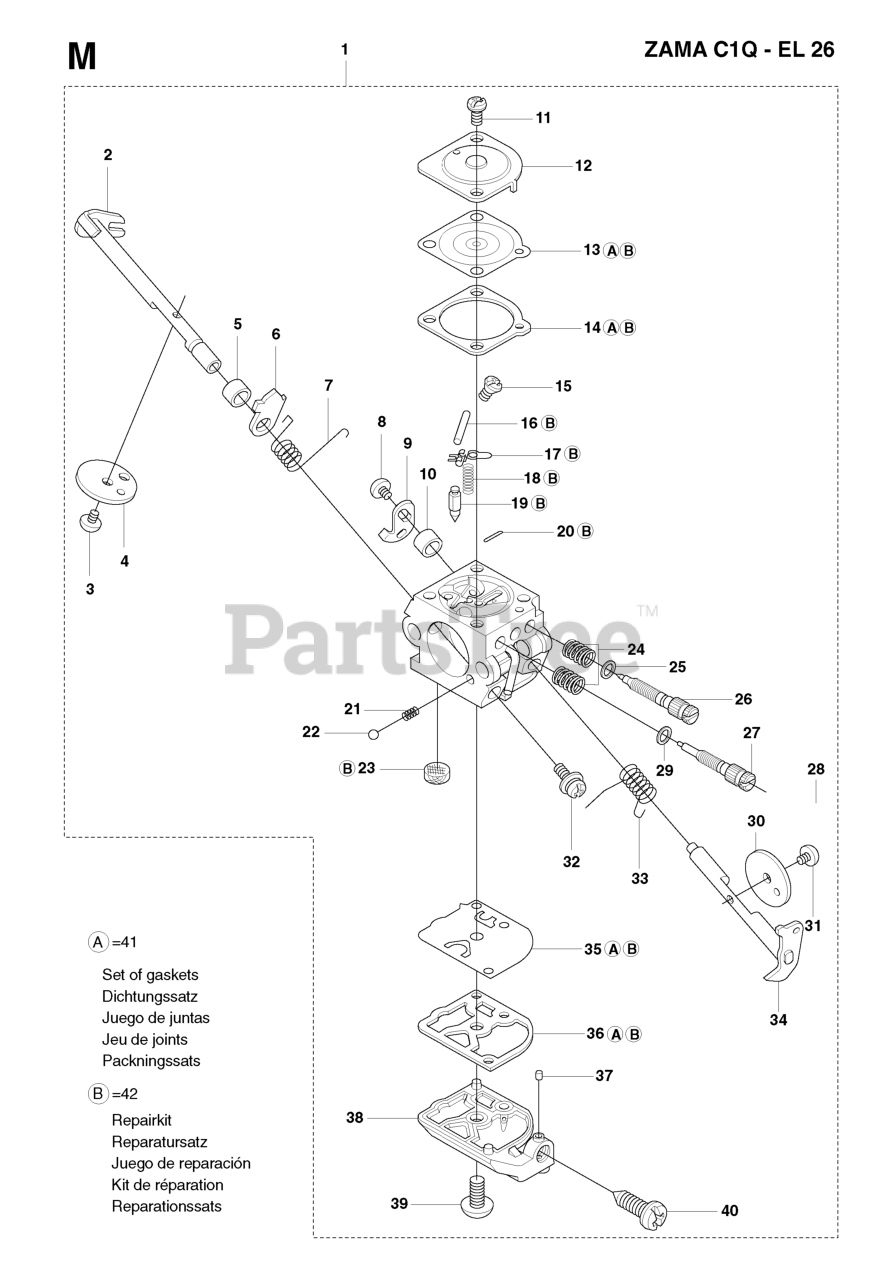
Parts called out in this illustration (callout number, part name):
1	CARBURETOR
2	CHOKE SHAFT
4	DISC
16	PIN RETAINING SCREW
18	SPRING
19	INLET NEEDLE
24	SPRING
26	LOW SPEED NEEDLE
27	NEEDLE HIGH SPEED
30	THROTTLE FLAP
33	SPRING THROTTLE
35	PUMP DIAPHRAGM
41	GASKET KIT (ZAMA GND39)
42	CARBURETOR KIT (ZAMA RB69)
